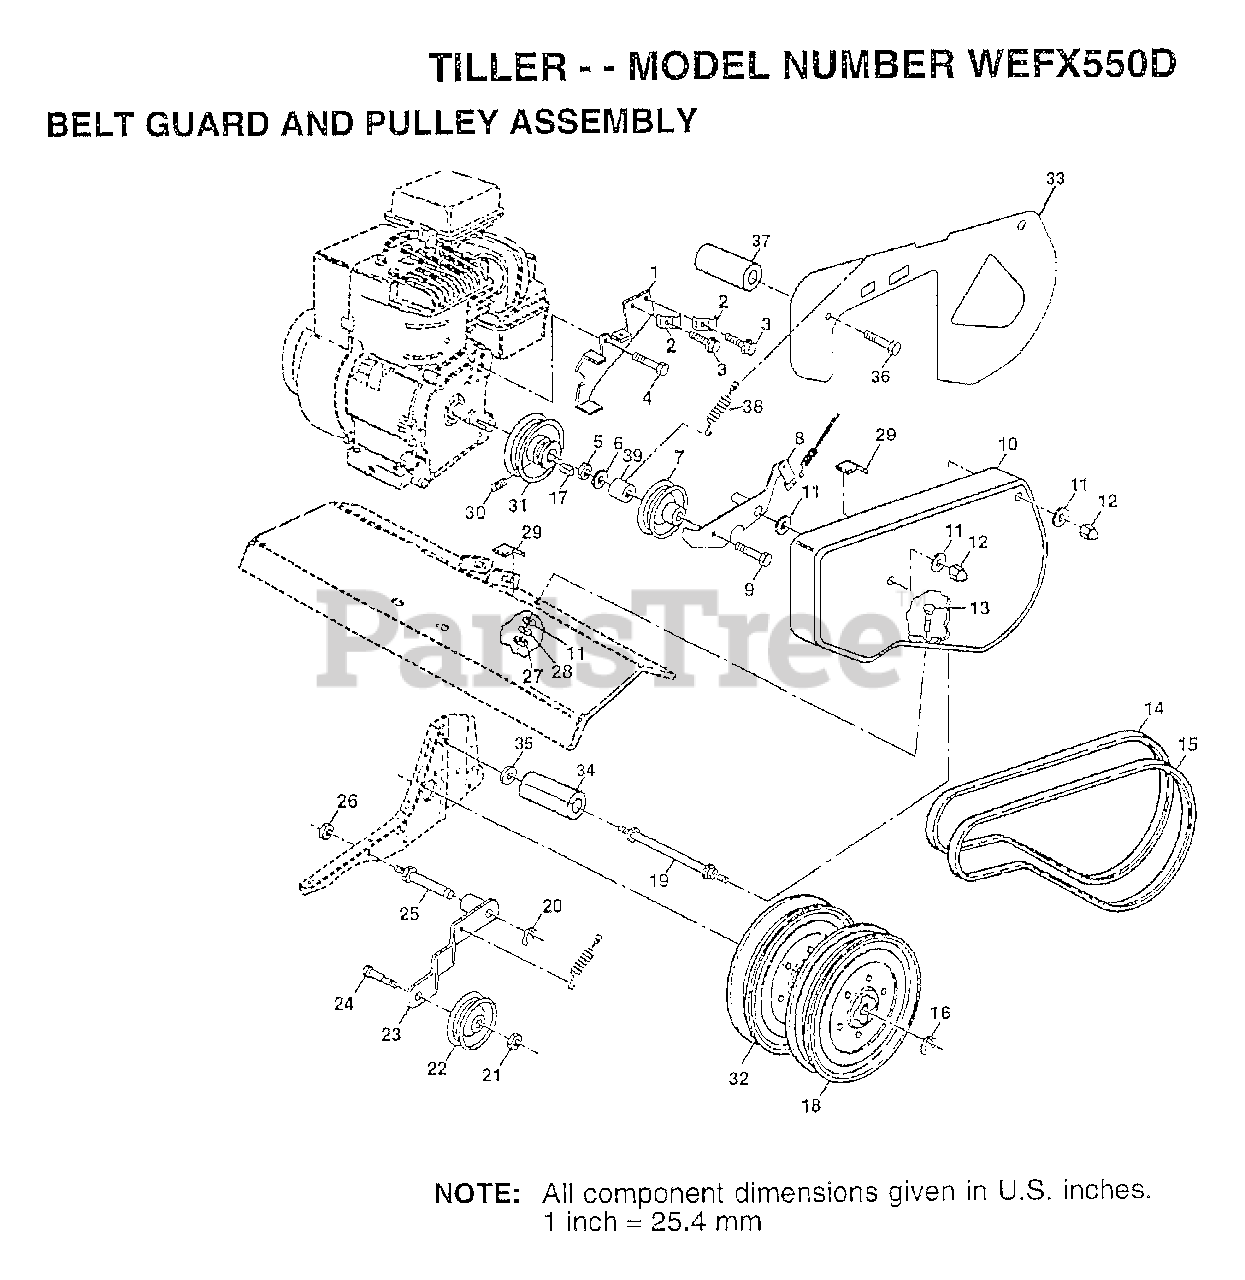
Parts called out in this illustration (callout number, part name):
1	ASSY.BRKT.BELT GUARD
2	CONDIUT CLIP T
4	BOLT.HEX.HEAD
5	NUTLOCK 3/8-16
6	WASHER
7	PULLEY W/SPACER
8	ASSY ARM REV.IDLR
10	"GUARD,BELT"
11	WASHER
12	NUT-CAP TI
13	BOLT T
14	BELT-V
17	KEY T
18	"SHEAVE,TRANS.""D"""
19	BOLT TI
20	KLIP RING TI
21	NUT
22	"PULLEY,IDLER"
23	"ARM, IDLER"
25	SHAFT IDLER TI
26	JAM NUT TI
28	LOCKWASHER
29	PAD IDLER TI
30	SET SCREW
31	ENGINE PULLEY TI
32	SHEAVE.TRANS
33	"SHIELD,BELT GUARD"
34	SPACER.SPLIT
35	WASHER
36	BOLT.5/16X24X1
37	SPACER.SPLIT
38	"SPRING,EXT"
39	SPACER.500X384X23
